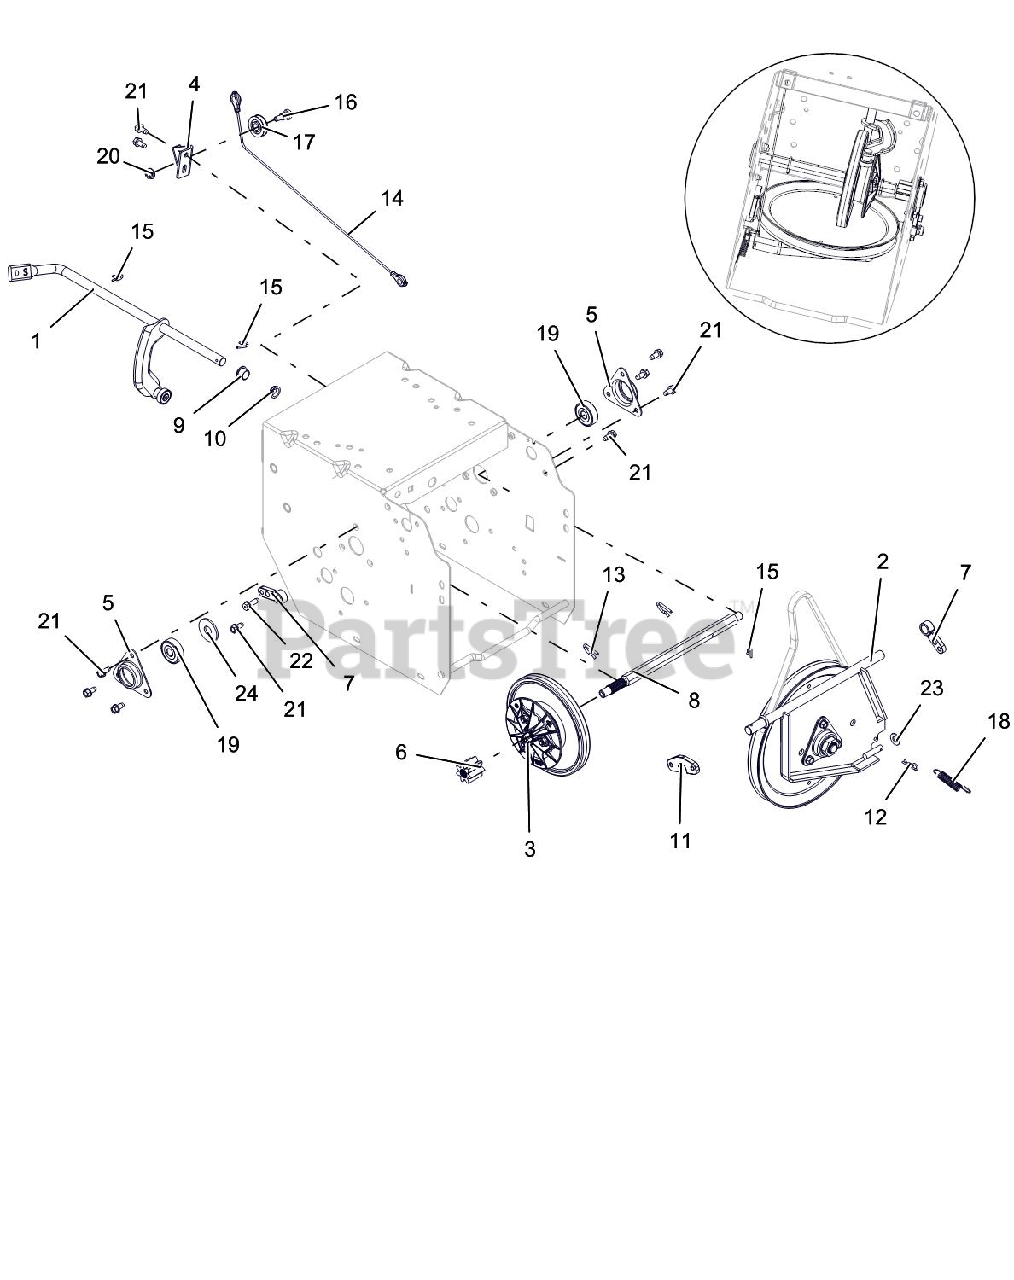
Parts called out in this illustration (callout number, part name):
1	ARM, SHIFT-SMALL DASH (ASSY)
2	PLATE, SWING - ASSEMBLY
3	DISC, FRICTION DRIVE-ASSEMBLY
4	BRACKET, CABLE PULLEY
5	FLANGE, BEARING
6	GEAR, PINION, 7 TOOTH W/SPLINE
7	SUPPORT BUSHING, SWING GATE
8	SHAFT, HEX W/SPLINE
9	BUSHING, POLYLINER-.50 SPLIT
10	BUSHING, POLYLINER-.50 SNAPIN
11	SPACER, SWING GATE
12	PIN-HAIR INT .08X.18X1.18 YWZC
13	PIN, SPRING CLIP
14	CABLE, LOWER TRACTION (CMPCT)
15	CLIP, SPRING
16	BOLT, SHLDR-.375X.375X.25-20
17	PULLEY, CABLE
18	SPRING, EXT. .043X.438X1.64
19	BRG-BALL .437X1.375X.437
20	@NUT-LK-CTR-FLG .25-20 YWZC
21	SCR-TAP .25-20X.50 HWH TR YWZ
22	SCR-TAP-PM .25-20X.75 TR YWZ
23	@WSHR-FL-STL.344X.688X.065YWZC
24	@WSHR-FL-STL.563X1.38X.109YWZC
